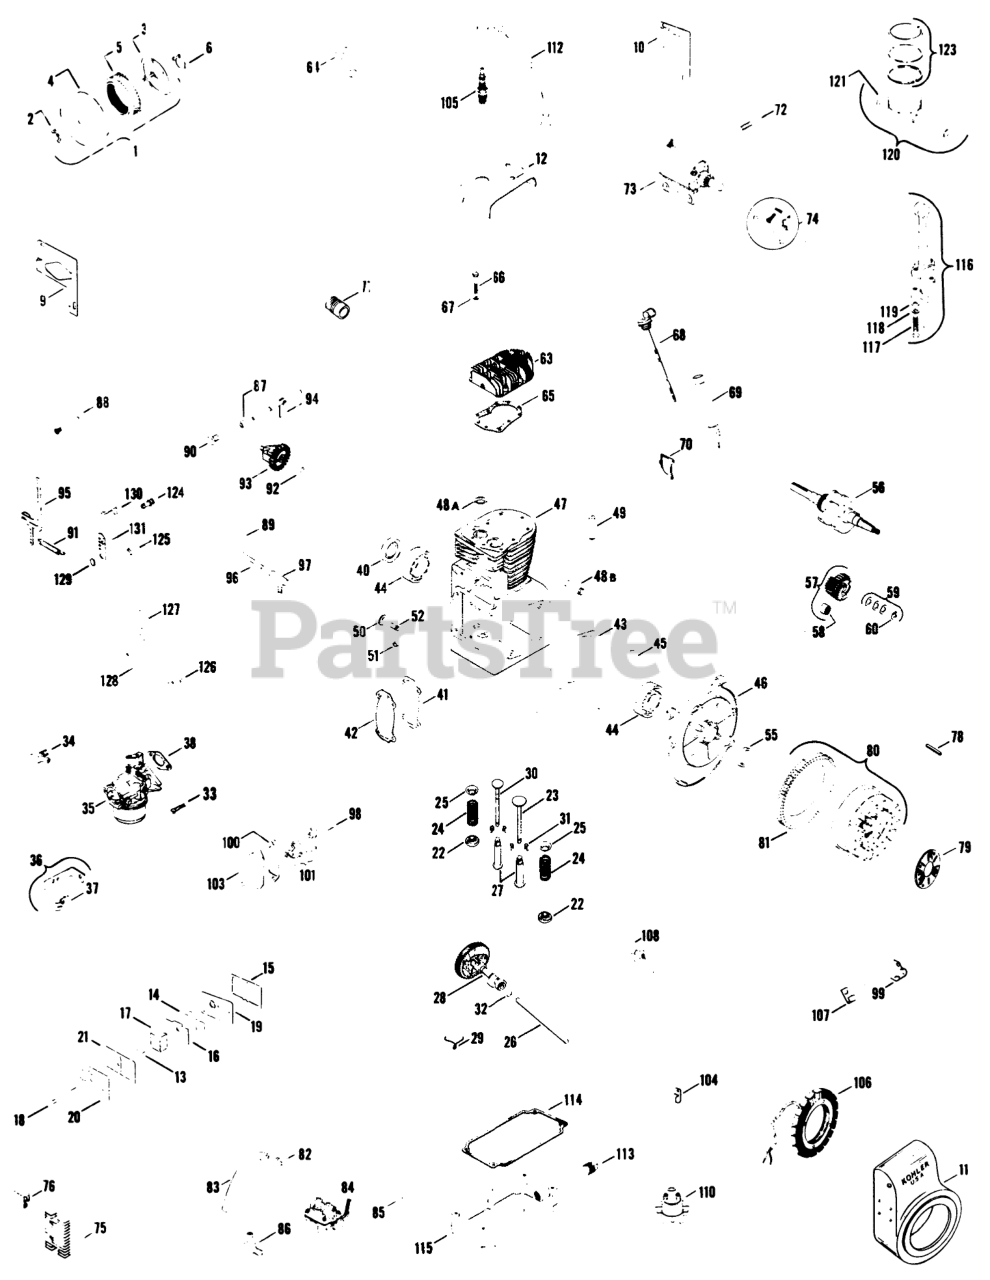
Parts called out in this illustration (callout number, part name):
1	Cleaner-Air Assembly
2	Nut-Wing
3	Base-Air Cleaner
4	Cover-Air Cleaner
5	Element
6	Gasket-Air Horn
9	BaffLe side air
10	Baffle cylinder
11	Housing-Blower
12	Baffle-Head
13	Seal
14	Reed
15	Gasket
16	Baffle breather
17	Filter Breather
18	Stud, valve cover
19	Plate
20	Cover valve
21	Gasket
22	Retainer-Spring
23	Valve-Intake
24	Spring
25	Retainer-Spring
26	Pin (Service)
27	Tappet
28	Camshaft-assembly
29	Spring-Actuating
30	Valve, exhaust
31	Keeper, Valve
32	Spacer
33	Screw sitd. hd.
34	Elbow
35	Carburetor-assembly
36	Bracket, choke
37	Clip
38	Gasket
40	Seal rear oil
41	Gasket
42	Cover
43	Gasket
44	Ball Bearing
45	Gasket
46	Plate Bearing
47	Block, cylinder-assembly (Use B-237416 Miniblock)
48A	Insert
48B	Shaft
49	Guide Valve
50	Plug
51	Bearing
52	Shaft-Govemor
55	Seal, Front OiI
56	Crankshaft
57	Gear
58	Bearing,needle
59	Kit-Spacer
60	Retainer
63	Belt Guide
64	Lift Cable
65	Gasket-Head
66	Screw
66	Screw-H.C.
67	Washer
68	Dipstick
69	Tube, fill
70	Gasket
72	Screw
73	Starter
74	Kit, Brush & Spring
75	Regulator
76	Connector
78	Key
79	Screen grass
80	Flywheel-Assembly
81	Gear Ring
82	Clamp
83	Line Fuel
84	Pump, fuel
85	Gasket, pump
86	Elbow
87	Spacer
88	Pin-GovemorStop
89	Retainer Rod
90	Bushing
91	Spring-Governor
92	Washer
93	Gear, Governor
94	Shaft, Governor
95	Lever, Governor
96	Rod ball joint
97	Ball Joint
98	Rod, breaker
99	Clip
100	Gasket, Cover
101	Breaker
103	Cover breaker
104	Clip
105	Plug, spark
106	Stator
107	Clip
108	Condenser
110	Coil
112	Kit, Hi-Tension
113	Plug
114	Gasket
115	Base, oil pan
116	Rod, Connecting
117	Screw, connecting rod
118	Washer
119	Washer
120	Piston-assembly (Std.) (Includes pin & retainers)
121	Pin, Retainer
123	Ring set-Std. & .003 (Svc.)
124	Clamp, swivel wire
125	Spacer
126	Retainer, rod
127	Bellcrank
128	Rod, throttle
129	Washer, tension
130	Bracket, adjusting screw
131	Bracket, speed control
